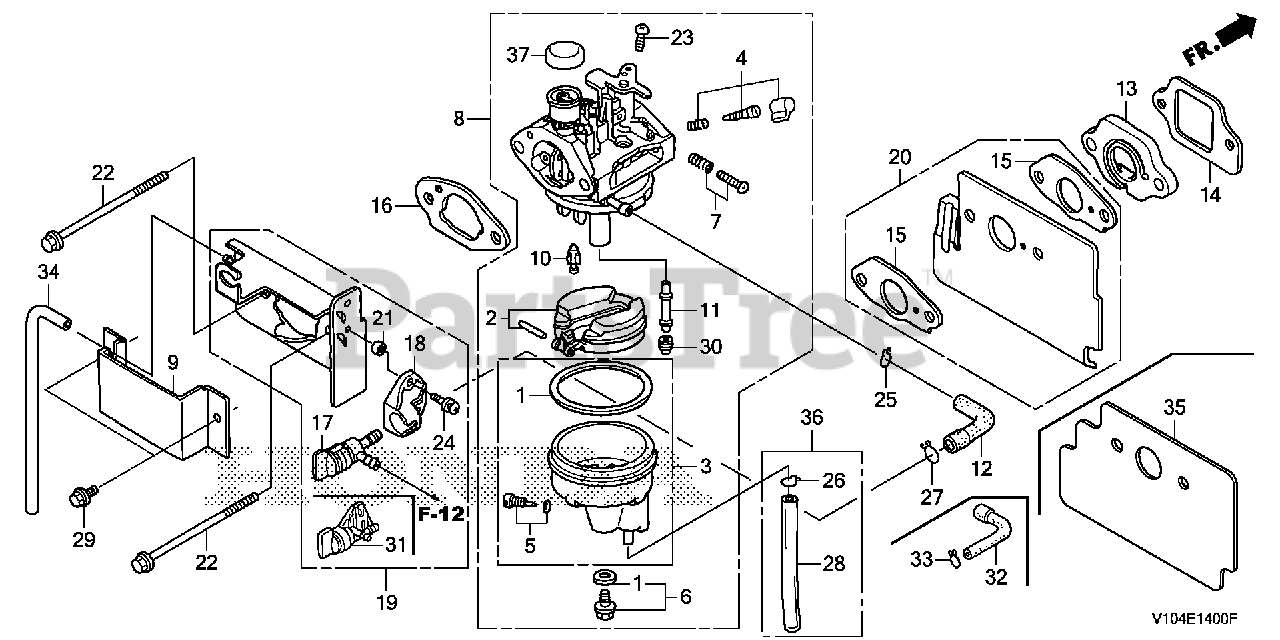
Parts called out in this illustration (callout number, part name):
1	GASKET SET
2	FLOAT SET
3	CHAMBER SET, FLOAT
4	SCREW SET (CARBURETOR NO.)
5	SCREW SET, DRAIN (ADVENTURE GREEN) (CARBURETOR NO.)
6	SCREW SET
7	SCREW SET (THROTTLE STOP) (CARBURETOR NO.)
8	CARBURETOR ASSY. (BB61C B)
9	GUARD, CARBURETOR
10	VALVE, FLOAT (CARBURETOR NO.)
11	NOZZLE, MAIN
12	TUBE, FUEL
13	INSULATOR, CARBURETOR
14	GASKET, INSULATOR
15	GASKET, CARBURETOR
16	GASKET, CARBURETOR (Honda Code 5580253). (CHOKE SIDE)
17	PETCOCK ASSY.
18	BRACKET, PETCOCK
19	STAY ASSY., PETCOCK
20	GUIDE, AIR
21	COLLAR, FR. TURN SIGNAL
22	BOLT, FLANGE (6X79) (CT200)
23	SCREW, PAN (5X6)
24	SCREW-WASHER (5X10)
25	CLIP, TUBE (B10)
26	CLIP, TUBE (B6.5)
27	CLIP, TUBE (C11)
28	BULK HOSE, VINYL (4X7X8000) (95003-07(95003-07001-60M) (CARBURETOR NO.)
29	BOLT, FLANGE (6X8)
30	JET, MAIN (#68) Use up to Engine SN BB30A D.
30	JET, MAIN (#70) Use up to Engine SN BB30A D.
30	JET, MAIN (#72) Use from Engine SN 6185281.
34	TUBE, AIR VENT
